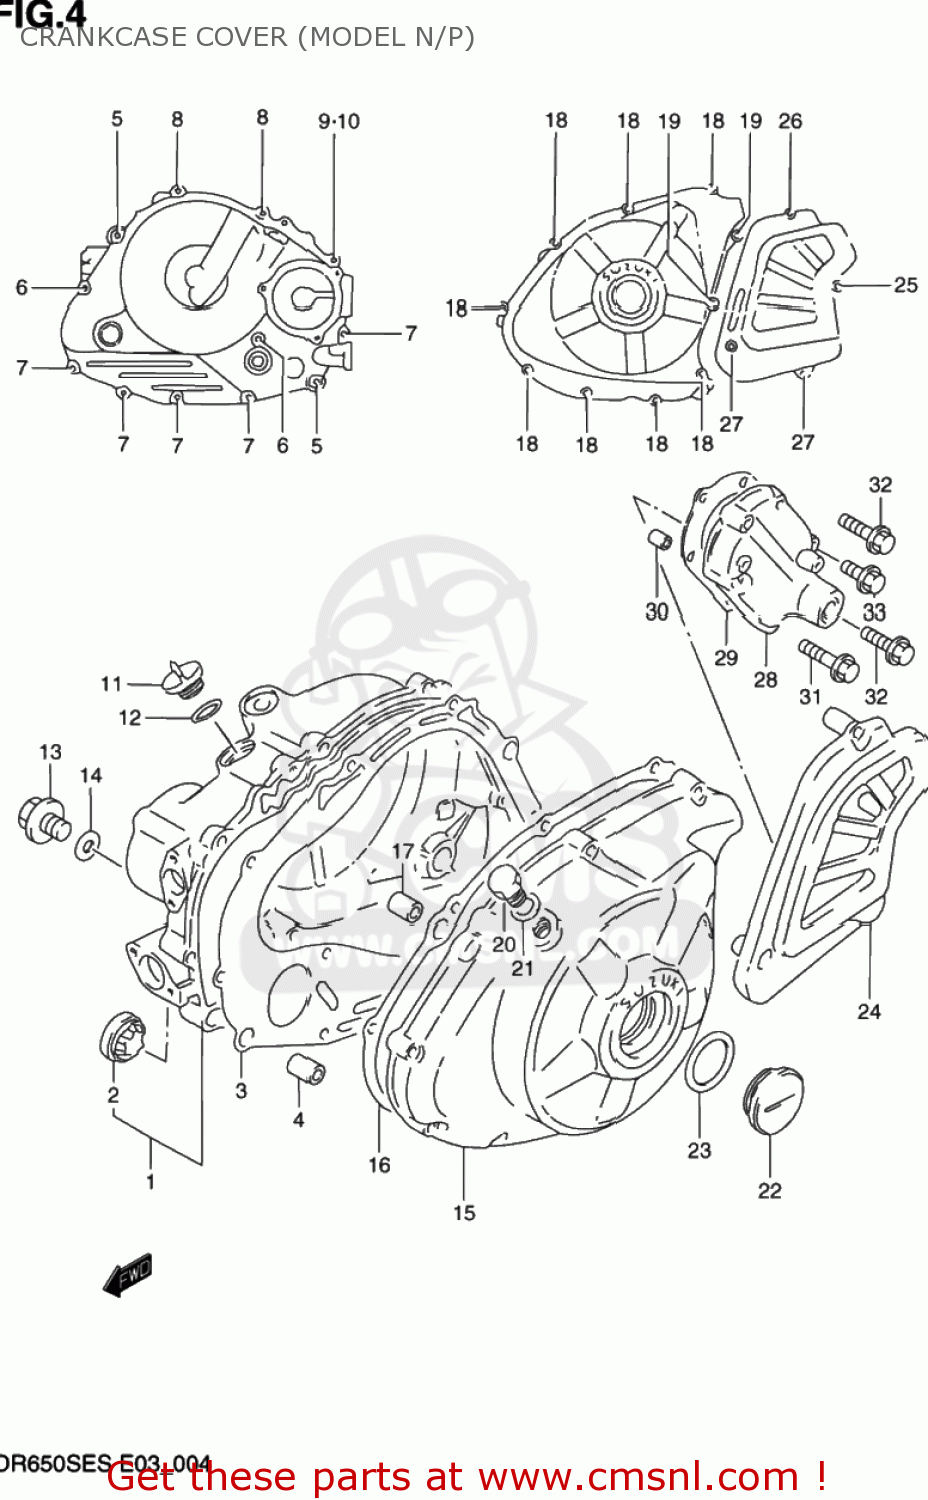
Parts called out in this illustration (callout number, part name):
1	COVER,CLUTCH
2	LENS,OIL LEVEL CHECK
3	GASKET,CLUTCH COVER (NAS)
4	PIN
5	BOLT
6	BOLT
7	BOLT
8	BOLT
9	BOLT 6X25
10	WASHER
11	PLUG
12	O RING(D:3.1,ID:16.8)
13	PLUG(14X12)
14	GASKET(14X19.2X2) (NAS)
15	COVER,GENERATOR
16	GASKET,MAGNETO COVER (NAS)
17	PIN
18	BOLT
19	BOLT
20	PLUG,12X9
21	GASKET(12.1X16.2X3.7) (NAS)
22	PLUG (36X10)
23	O RING(D:3.1,ID:32.7)
24	COVER,ENGINE SPROCKET
25	BOLT
26	BOLT
27	BOLT
28	COVER,GEAR SHIFT
29	GASKET,GEAR SHIFT COVER (NAS)
30	PIN
31	BOLT
32	BOLT
33	BOLT
